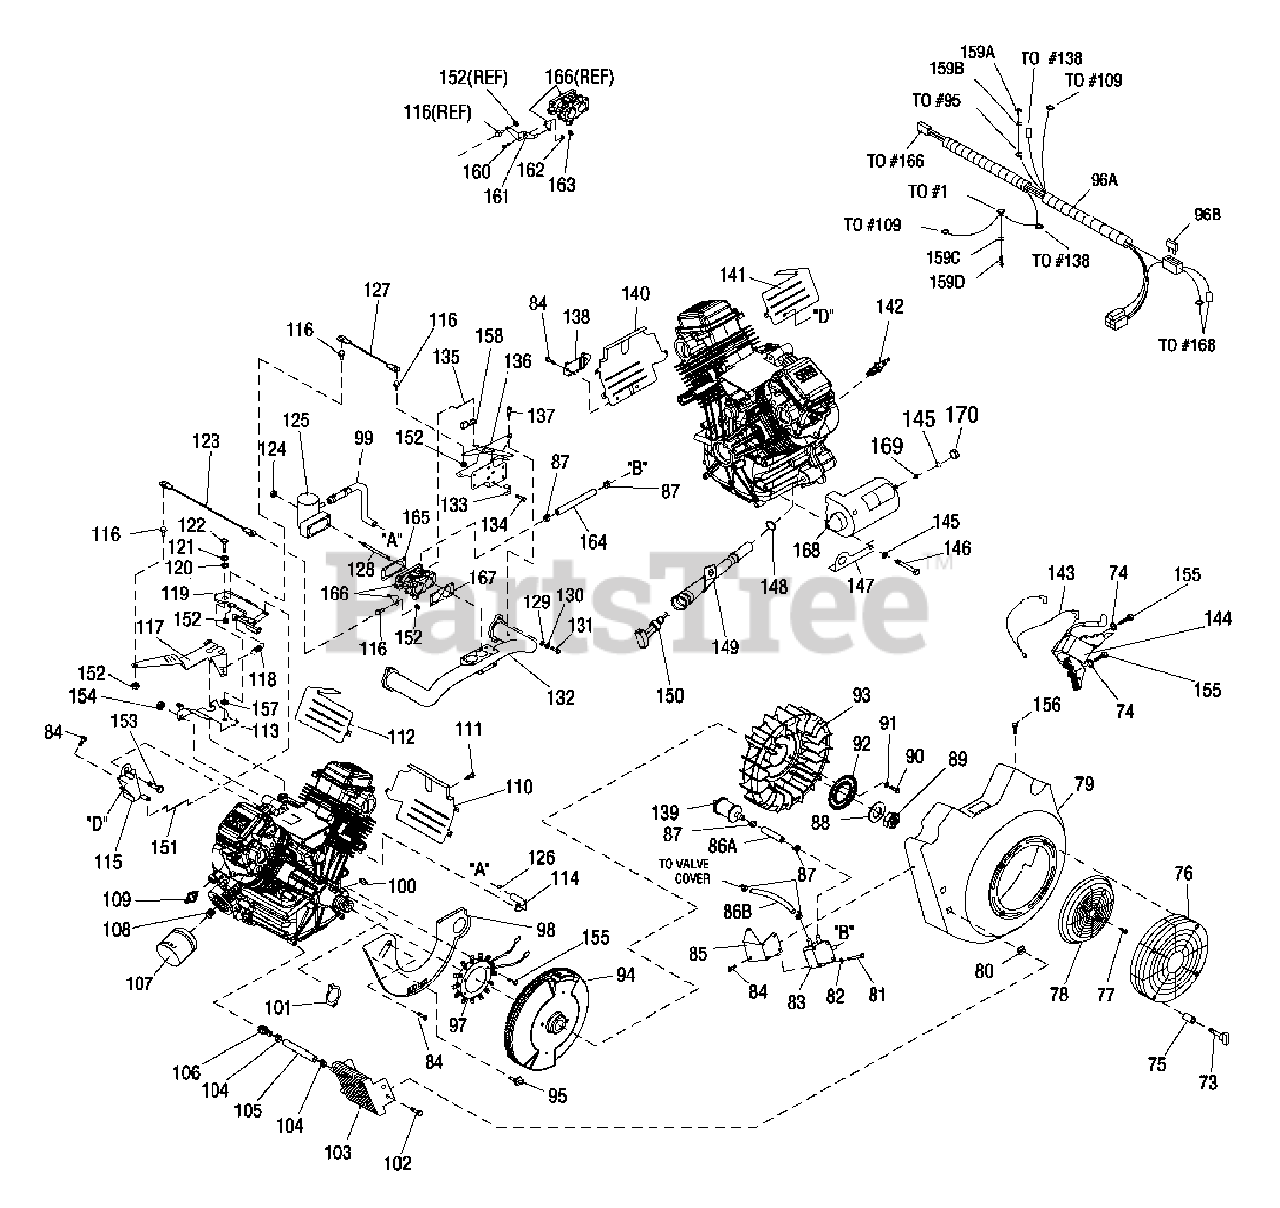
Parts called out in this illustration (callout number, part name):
73	KNOB AIR CLEANER
74	WASHER, LOCK M6-1/4"
75	SPACER, ROTATING SCREEN GUARD
76	GUARD, ROTATING SCREEN
77	SCREW, #10 SHEET METAL
78	SCREEN, ROTATING
79	HOUSING, BLOWER VERTICAL
80	NUT, GROMMET 1/4 PLUG
81	SCREW PPHM M4-0.7 x 40
82	WASHER, LOCK M4
83	PUMP, IMPULSE
84	SCREW TAPTITE M6-1.0 x 10 YELLOW CHROME
85	BRACKET, FUEL PUMP
86A	HOSE 1/4" ID x 2" LONG
86B	HOSE 1/4" ID x 7" LONG
87	CLAMP HOSE BAND 1/4
88	WASHER, M24
89	NUT, HEX M24
90	SCREW HHC M8-1.25 x 10 G8.8
91	WASHER SHAKEPROOF INT M8 SS
92	PLATE, FAN
93	FAN, NYLON
94	FLYWHEEL ASSEMBLY
95	INSULATOR ASSEMBLY IGNITION
96A	VS WIRE HARNESS W/ FUSE
96B	30 AMP FUSE
97	ASSEMBLY, STRATOR W/LUGS
98	PLATE, BACKING WITH OIL COOL
99	ASSY. BREATHER TUBE
100	KEY, WOODRUFF 4 x 19D
101	GASKET, MANIFOLD / PORT
102	PLASTITE, 1/4 - 15 x 3/4
103	COOLER, OIL
104	CLAMP HOSE .38 - .87
105	HOSE, 3/8" I.D x 6" LONG
106	BARBED STR 1/4NPT x 3/8 WITH VIBRA SEAL
107	FILTER OIL D 69 x 64 LONG
108	NIPPLE, 34"-16 UNF
109	SWITCH, OIL PRESS
110	WRAPPER, LOWER CYLINDER 1
111	SCREW THTT #10-24 x 3/8"
112	WRAPPER, UPPER CYLINDER 1
113	BRACKET, SUPPORT-GOVERNOR ADJUST
114	HOSE, BLOWER HSG TO BREATHER
115	ASSY, IDLE SPEED SUPPORT BRACKET
116	STUD, BALL M3-0.5
117	ASSY, GOVERNOR LEVER
118	SPRING, GOVERNOR
119	ASSY, IDLE SPEED ADJUST W/ GROMMET
120	WASHER, FLAT M5
121	WASHER LOCK M5
122	SCREW, HHC M5-0.8 x 10
123	ROD, GOVERNOR
124	NUT LOCK FLANGE M6-1.0
125	ADAPTOR, CARB-AIRBOX, M6 BOSSES
126	HOSE CLAMP, BAND 12 MM I.D.
127	ASSEMBLY, IDLE SPEED ADJUSTMENT ROD
128	STUD, METRIC
129	WASHER, FLAT M8
130	WASHER, LOCK M8
131	SCREW, SHC M8-1.25 x 30
132	MANIFOLD.INTAKE 2BBL CARB
133	CLAMP, 3/16" COATED CABLE
134	SCREW, PPHM M5-0.8 x 12
135	ROD, CHOKE
136	ASSY, BELDEN BRACKET W/BELLCRANK
137	SCREW HHFC M6-1.0 x 8MM
138	REGULATOR, 20 AMP
139	FILTER, FUEL
140	WRAPPER, LOWER CYLINDER 2
141	WRAPPER, UPPER CYLINDER 2
142	SPARK PLUG BKR4E
143	ASSEMBLY, GROUND WIRE
144	ASSEMBLY, IGNITION COIL
145	WASHER, LOCK M8-5/16
146	SCREW, HHC M8-1.25 x 85 G8.8
147	LIFT HOOK, STARTER
148	O-RING, OIL CLR
149	TUBE, DIPSTICK
150	ASSEMBLY, DIPSTICK W/ HANDLE
151	ROD, IDLE ADJUSTMENT
152	NUT, LOCK HEX M3-0.5
153	SCREW, SHC M10-1.5 x 75 G10.9
154	NUT, LOCK FL-SERRATED M10-1.5
155	SCREW, TAPTITE M6-1.0 x 25
156	SCREW, FHHC M6-1.0 x 12 W/M5 HEX
157	WASHER NYLON 0.357" I.D.
158	BUSHING, GOVERNOR ROD
159A	NUT HEX #8-32
159B	WASHER LOCK #8-M4
159C	WASHER LOCK M3
159D	SCREW PPHM M3-0.5 x 8
160	SCREW, PPHM #10-32 X3/8
161	BRACKET, THROTTLE
162	WASHER, LOCK #10
163	NUT, HEX #10-32
164	HOSE 1/4"ID x 11" LONG
165	GASKET, CARB TO SPACER
166	CARBURETOR DENI GVT990
167	GASKET, MANIFOLD TO CARB
168	STARTER, V-TWIN ENGINE
169	WASHER, FLAT M8
170	NUT, HEX M8-1.25 G8
